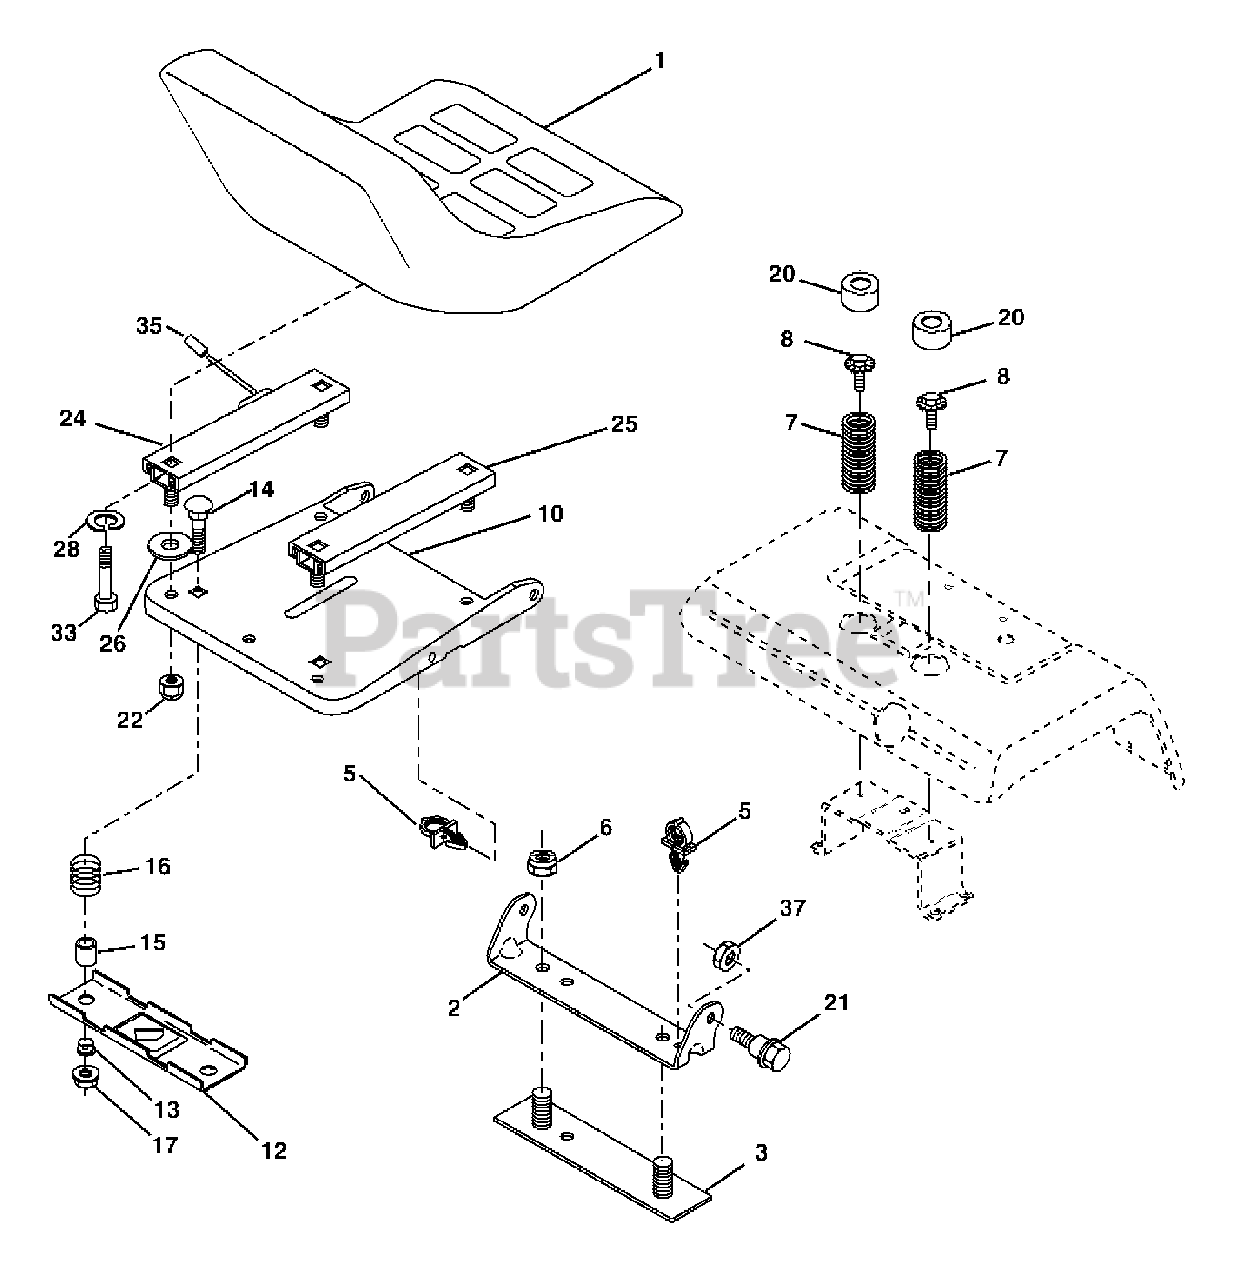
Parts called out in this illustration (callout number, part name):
1	Seat
2	Bracket, Pivot Seat
3	Strap Asm Fender
5	Clip, Push In Hinged
6	Nut, Crownlock 3/8-16
7	Spring, Seat Cprsn
8	Bolt 5/16-18 Unc x 3/4
10	Pan, Seat
12	Bracket, Mounting Switch
13	Bushing, Snap
14	Bolt, Carriage 1/4-20 x 1-1/2
15	Spacer, Split
16	Spring, Cprsn
17	Nut, Lock 1/4 Lge Flg Gr. 5
20	Cap Spring Seat
21	Bolt, Shoulder 5/16-18
22	Nut Crown Lock 5/16-18
24	Track Slide Seat LH
25	Track Slide Seat RH
26	Washer 11/32 x 5/8 x 12 Ga.
28	Washer Split
33	Bolt Fin Hex 5/16-18 x 3/4
35	Cap Vinyl
37	Nut, Crownlock 5/16-18
